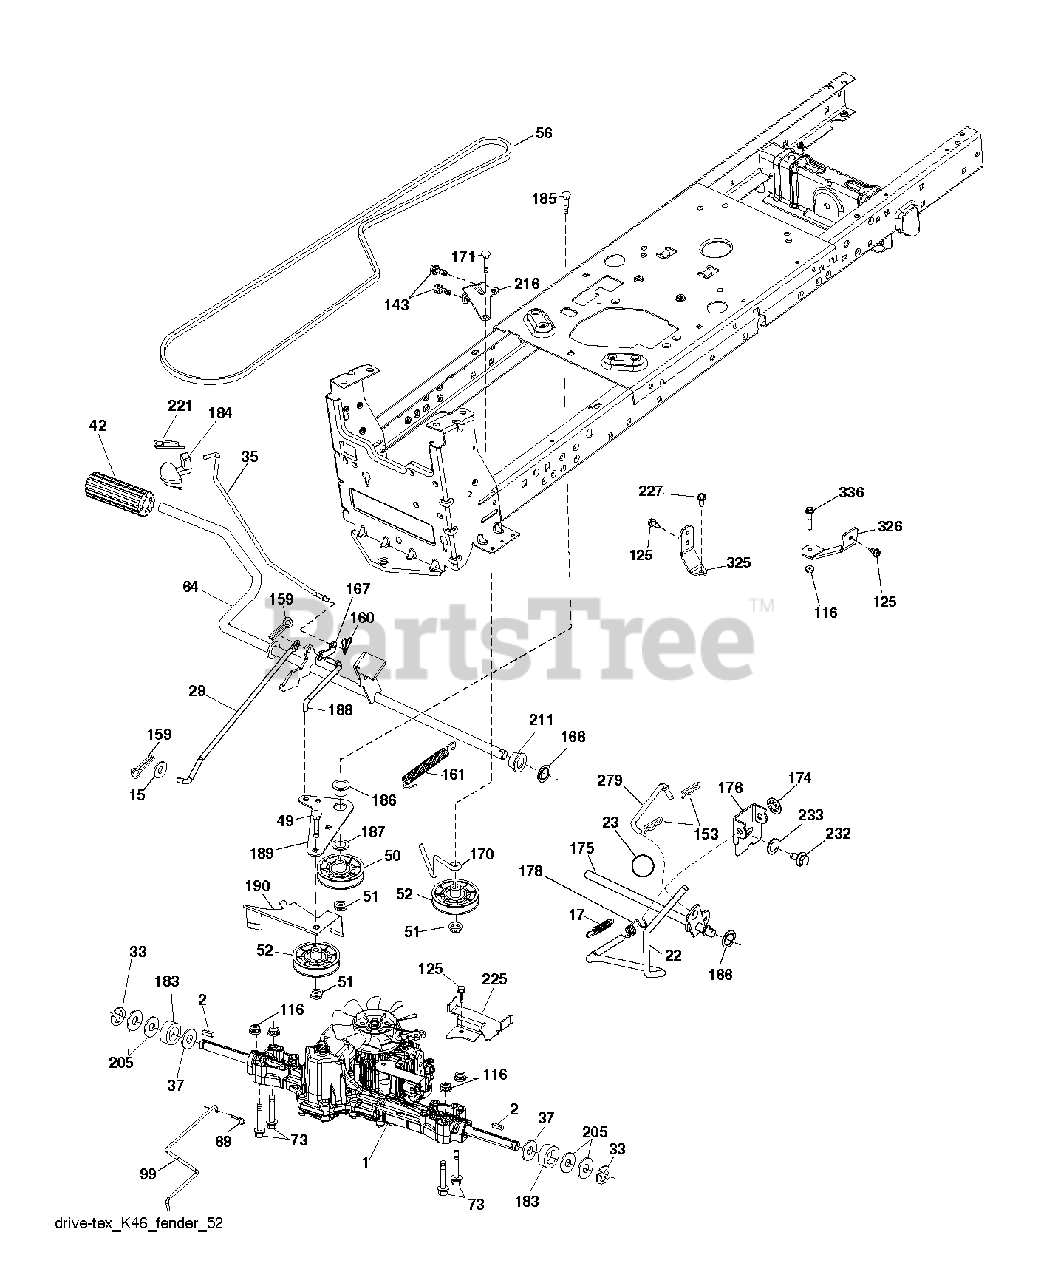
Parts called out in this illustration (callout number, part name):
2	SQUARE KEY
15	WASHER
17	SPRING.BRAKE.K46.GREEN
23	KNOB.DELUXE.(PISTOL.GRIP).BLAC
29	ROD.BRAKE.K46
35	ROD.CNTRL.PARK.PREDATOR.LT.TEX
37	WASHER.HARDENED
42	PEDAL COVER T
50	IDLER.FLAT.910.OFFSET
51	NUT LOCK FLG 3/8-16 UNC
52	IDLER.V-GROOVE.910.OFFSET
56	V-BELT.MOWER.92.40.42/K46
64	SHAFT.ASM.PEDAL.BRAKE.
69	HAIRPIN.SOFT.ZINC.059X1.125
99	ARM.PIVOTING.TCRD.GEN2.5.BAGGE
116	NUT LOCK HEX FLANGE 5/16-18
125	SCREW
143	SCR 5/16-18 X 1/2 SELFTAP ZN
153	RETAINER M
159	COTTER PIN
160	RETAINER CLIP
161	SPRING, RETURN LT
166	NUT.PUSH.625
167	LATCH.BRAKE.SPRING
170	KEEPER.V-IDLER.CENTER.
174	NUT.PUSH.500.2006
175	SHAFT ASM SHIFT
176	ARM.CLEVIS.ROD.SHIFT
178	SPRING.SHIFT.GT2006
183	SPACER AXLE
184	HANDLE.PARKNG BRK.PRED.LT.428
186	SPACER.RETAINER
187	WASHER 12/32X2X10GA
188	LINK.CLUTCH.GROUND DRIVE.LONG
189	BELLCRANK.GROUND.DRIVE.TEX.
190	KEEPER.BELLCRANK.DRIVE
211	BUSHING.SHAFT.BRAKE.HAND
216	BRACKET.PULLEY.IDLER.W/TEX
221	RETAINER.SPRING.CLIP.H
225	KEEPER.BELT.TRANSAXLE.K46
227	SCREW
232	BOLT FIN HEX 7/16-14 X 1
233	WASHER SERRATED
279	LINK.SHIFT.T/A.K46.FEND.TX
325	BRACKET.TRQ.STP.46.20".TIRE.LH
326	BRACKET.TRQ.STP.46.20".TIRE.RH
336	BOLT.5/16-18X1-3/4.FLANGED.HEX
